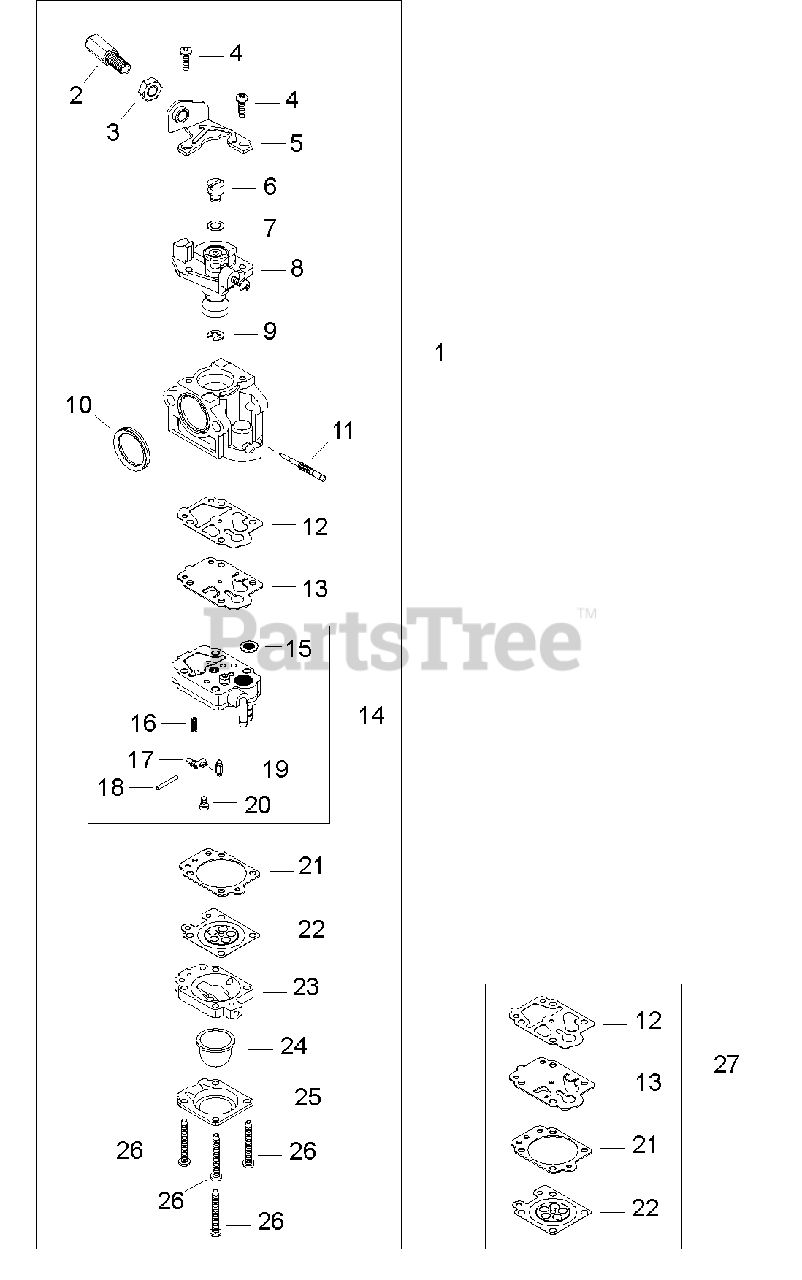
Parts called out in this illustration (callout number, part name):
1	CARBURETOR WYK
2	THROTTLE CABLE ADJUSTER
3	NUT
4	SCREW
5	BRACKET, CABLE
6	SWIVEL
7	WASHER
8	THROTTLE VALVE ASSY
9	RING, RETAINING
10	SEAL
11	NEEDLE - HIGH SPEED
12	GASKET, PUMP
13	DIAPHRAGM, PUMP
14	PUMP BODY ASSY
15	STRAINER
16	SPRING, METERING LEVER
17	LEVER, METERING
18	PIN, METERING LEVER
19	VALVE, INLET NEEDLE
20	SCREW, METERING LEVER PIN
21	GASKET, METERING
22	DIAPHRAGM, METERING
23	BASE, PURGE
24	BULB, PURGE
25	RETAINER, PURGE BULB
26	SCREW, PUMP COVER
27	DIAPHRAGM/GASKET KIT
